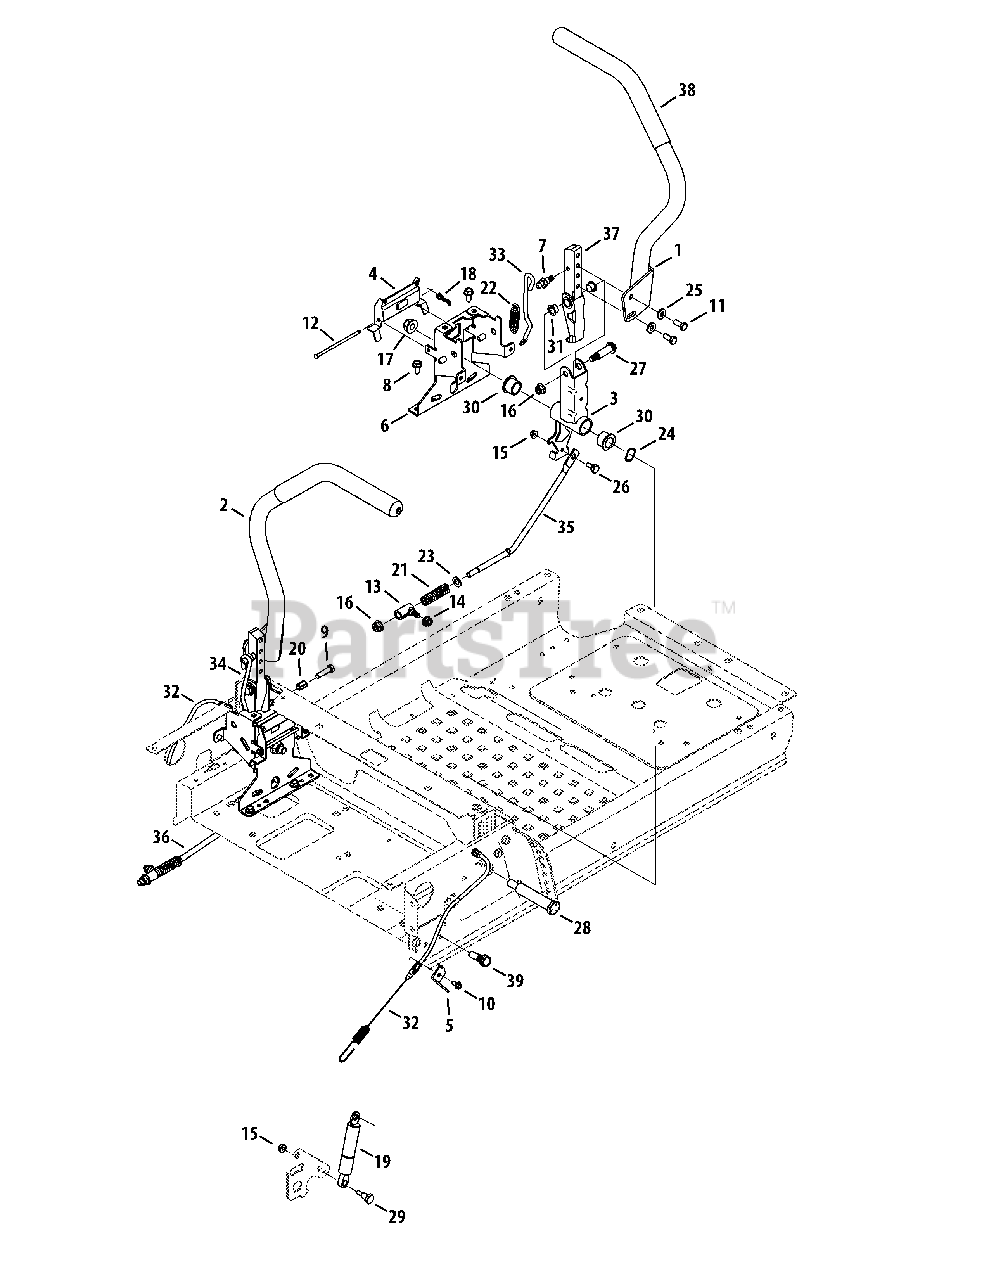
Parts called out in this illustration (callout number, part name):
1	RH Lapbar Lever Assembly
2	LH Labpar Lever Assembly
3	Lapbar Pivot Bracket
4	Brake Lever Actuator
5	Brake Cable Bracket
6	Lapbar Pivot Support Bracket
7	Screw, Shoulder Ball, 5/16-18 x .48
8	Hex Washer Screw, 5/16-18 x .750
9	Hex Cap Screw, 5/16-18 x 1.25
10	Hex Washer Screw, 1/4-20 x .500
11	Hex Head Screw, 5/16-18 x .75 Patch
12	Pin, .188 x 4.1
13	Ferrule, 3/8 ID x .420 Shldr
14	Flange Lock Nut, 5/16-18
15	Flange Lock Nut, 1/4-20
16	Flange Lock Nut, 3/8-16
17	Flange Lock Nut, 1/2-13
18	Bow-Tie Cotter Pin
19	Dampener, .87 OD x 7.06 Lg
20	Nut, 5/16-18
21	Compression Spring, .45 x 3.215
22	Extension Spring, .56 x 2.31 x .105
23	Flat Washer, .385 x .62 x .063
24	Washer, Wave, .785 x 1.0 x .012
25	Flat Washer, .344 x .750 x .120
26	Shoulder Screw, .375 Dia. x .181
27	Shoulder Screw, .498 Dia. x 1.296
28	Shoulder Screw, .75 x 3.25 x 1/2-13
29	Shoulder Screw, .395 Dia. x .56
30	Bearing, .75 x 1.00 x .73
31	Flange Bearing, .500 x .627
32	Park Brake Cable
33	Lapbar Detent Rod, RH
34	Lapbar Detent Rod, LH
35	Hydro Control Rod, RH
36	Hydro Control Rod, LH
37	Lower Arm
38	Lapbar Grip
39	Shoulder Screw, .395 Dia. x .83
